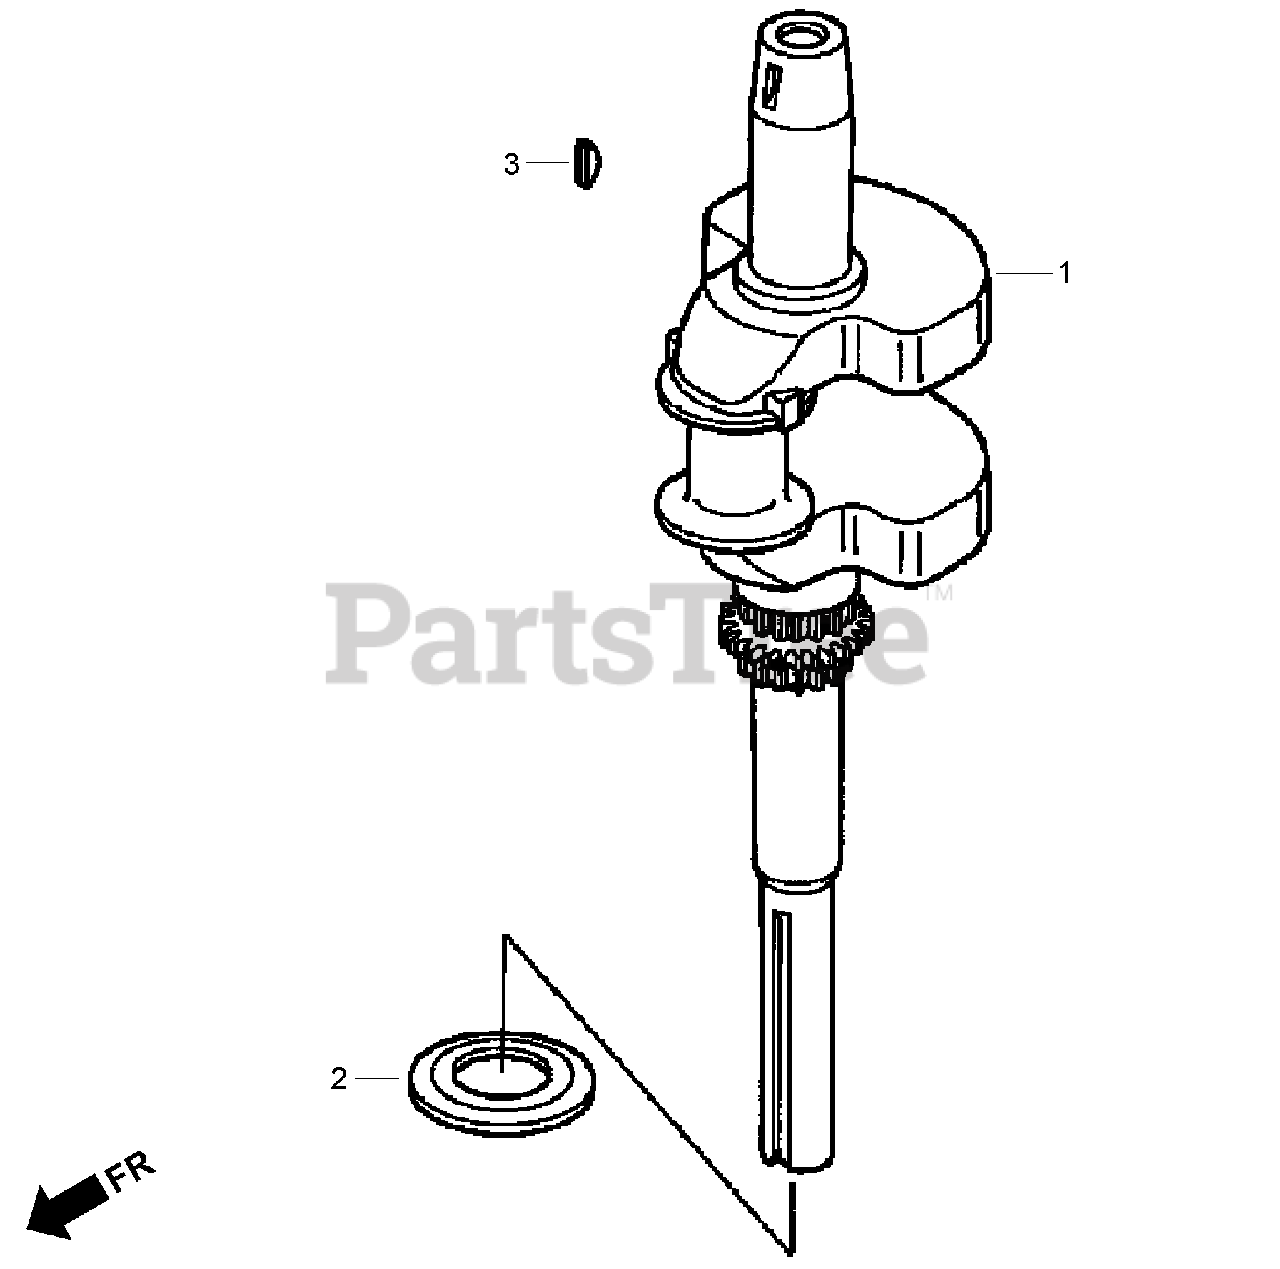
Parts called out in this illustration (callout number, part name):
1	CRANKSHAFT
2	WASHER-THRUST
3	KEY-WOODRUFF, SPECIAL (25X18)
